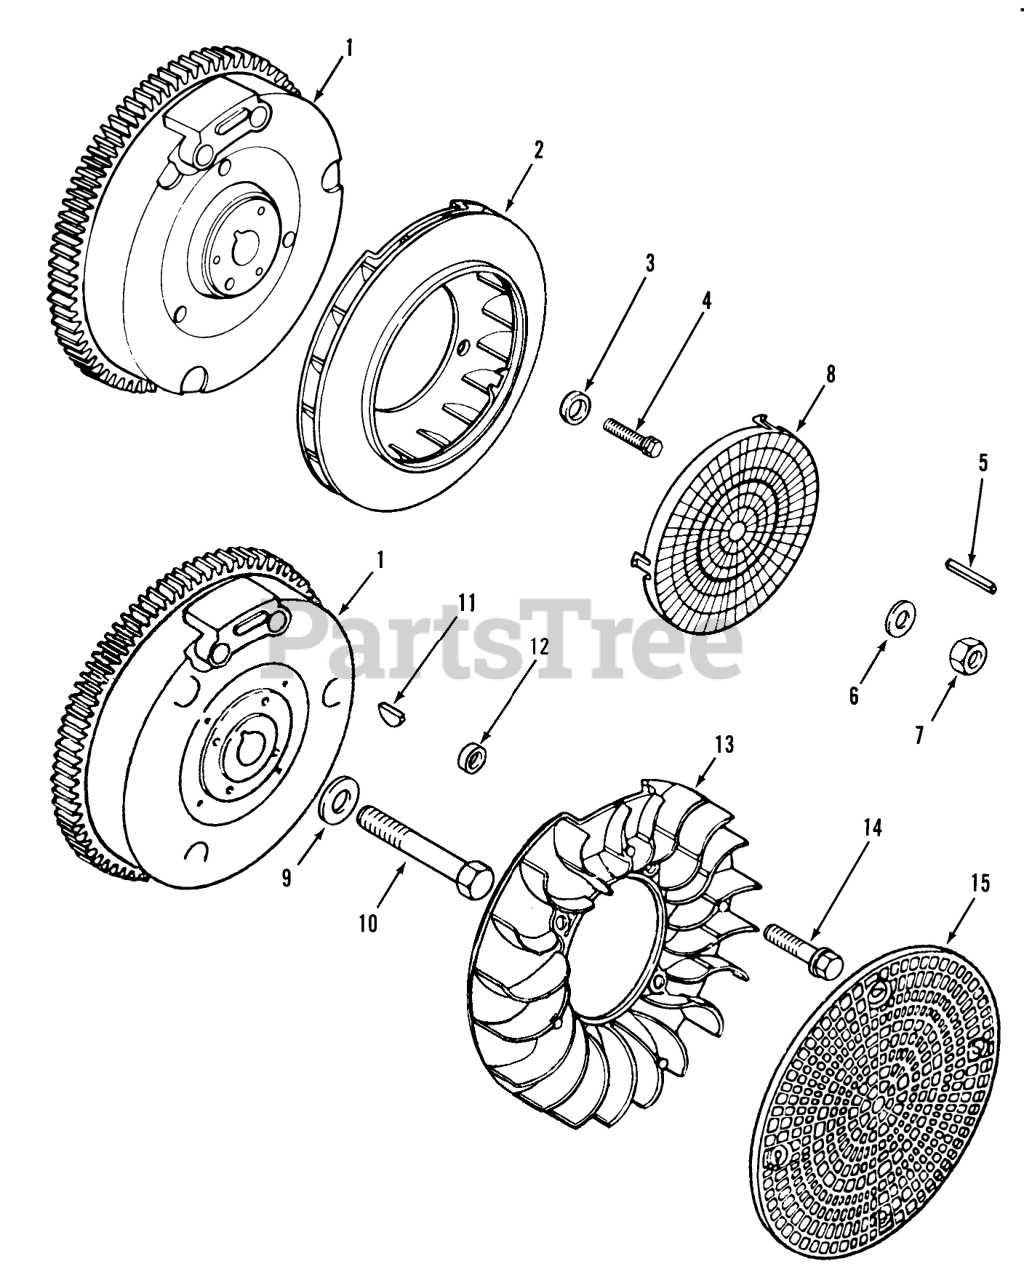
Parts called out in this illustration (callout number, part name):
1	Flywheel 308 Only
2	Fan 308 Only
3	Spacer 1/4 ID x 3/8 OD 308 Only
4	Hex Wash. Hd. Screw 1/4-20 x 1/2 308 Only
5	Sq. Key 3/16 x 1-3/8 308 Only
6	Plain Washer 5/8 308 Only
7	Hex Nut 5/8-18 308 Only
8	Grass Screen 308 Only
9	Plain Washer 13/32 ID, 1-3/8 OD
10	Hex. Mach. Screw 3/8-24 x 1-1/8
11	Key-Woodruff
12	Spacer
14	Screw-Hex. Hd.
15	Screen
